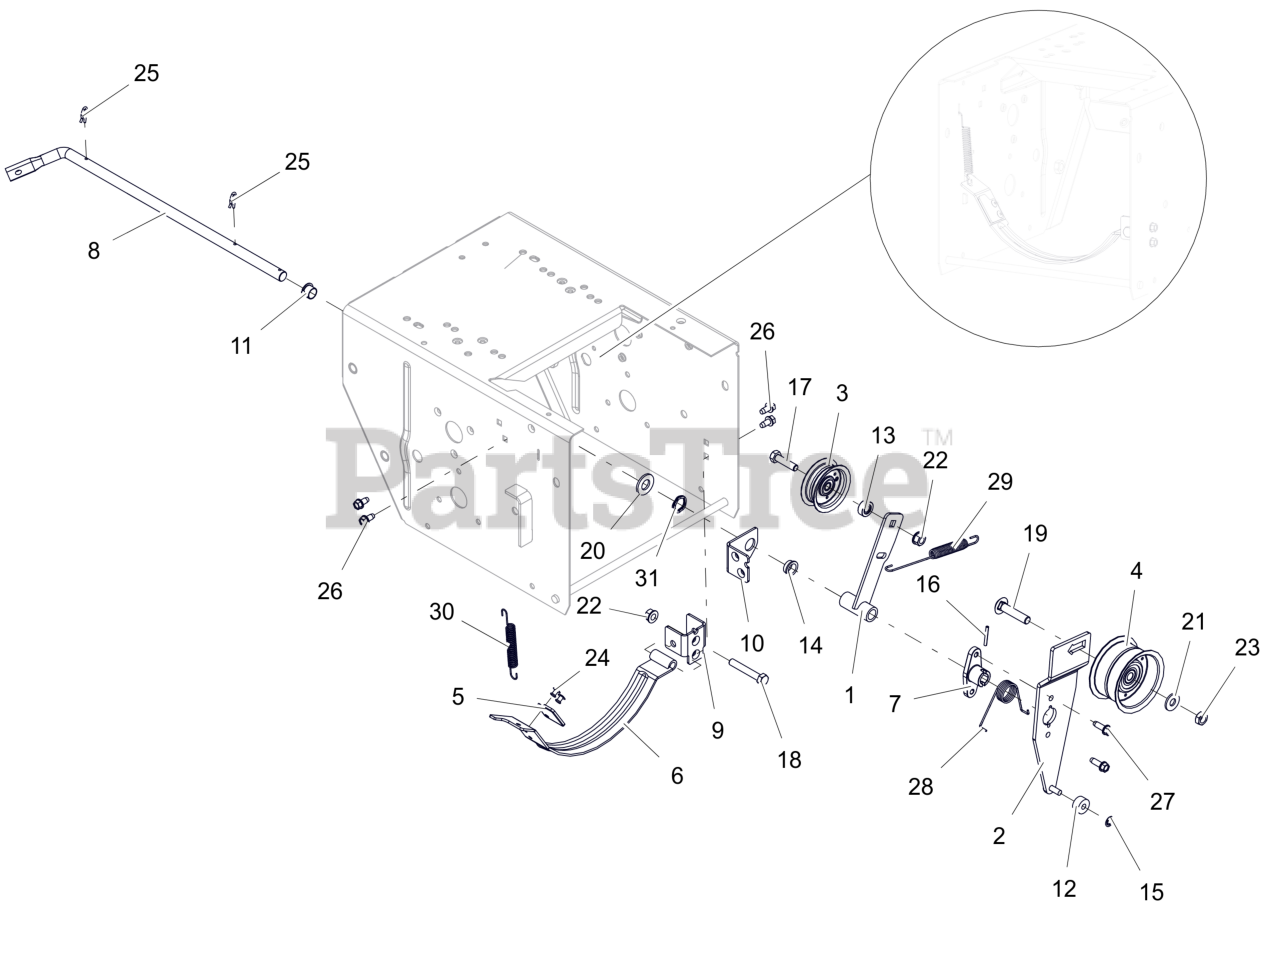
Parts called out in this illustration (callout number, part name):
1	ARM, IDLER -TRACTION
2	ARM, IDLER - ATTACHMENT
3	IDLER, FLAT - 2.00"
4	IDLER, FLANGE -2.75 OD X .375 ID
5	PAD, BRAKE
6	ARM, BRAKE-ATTACHMENT
7	HUB, BRAKE ARM
8	ARM, ATTACHMENT
9	PIVOT, BRAKE
10	BRKT, SUPPORT
11	BUSHING, POLYLINER-.50 SPLIT
12	BSHG,SLV .265 X .625 X .375
13	SPCR, BRG .315X.500X.358X.281
14	BSHG,FLANGE .500X.625X.270X.75
15	RG-RTNG-EXT .250X.010
16	PIN-ROLL .125X1.00
17	BLT, HEX .31-18X1.25 G5 ZCC
18	BLT, HEX .31-18X2.00 G5 ZCC
19	BLT, RHSSN .38-16X1.75 G5 ZCC
20	WSHR,FLT .531X1.062X.095 ZCC
21	WSHR,FLT .375X.875X.083 ZCC
22	NUT-LK-TOP-FLG .312-18 GF ZCC
23	NUT-LK-CTR-JAM .375-16 GB ZCC
24	RVT, POP .1875 ZCC
25	CLIP, SPRING
26	SCR-TAP .25-20X.50 HWH ZCC
27	SCR,TAP .25-20X.75 HWH TR ZCC
28	SG-TORS .067X.88
29	SG-TENS .06X.482X5.35
30	SPRING-EXT .437 X .438 X 2.64
31	WAVE SPRING .600X.875X.25FH
